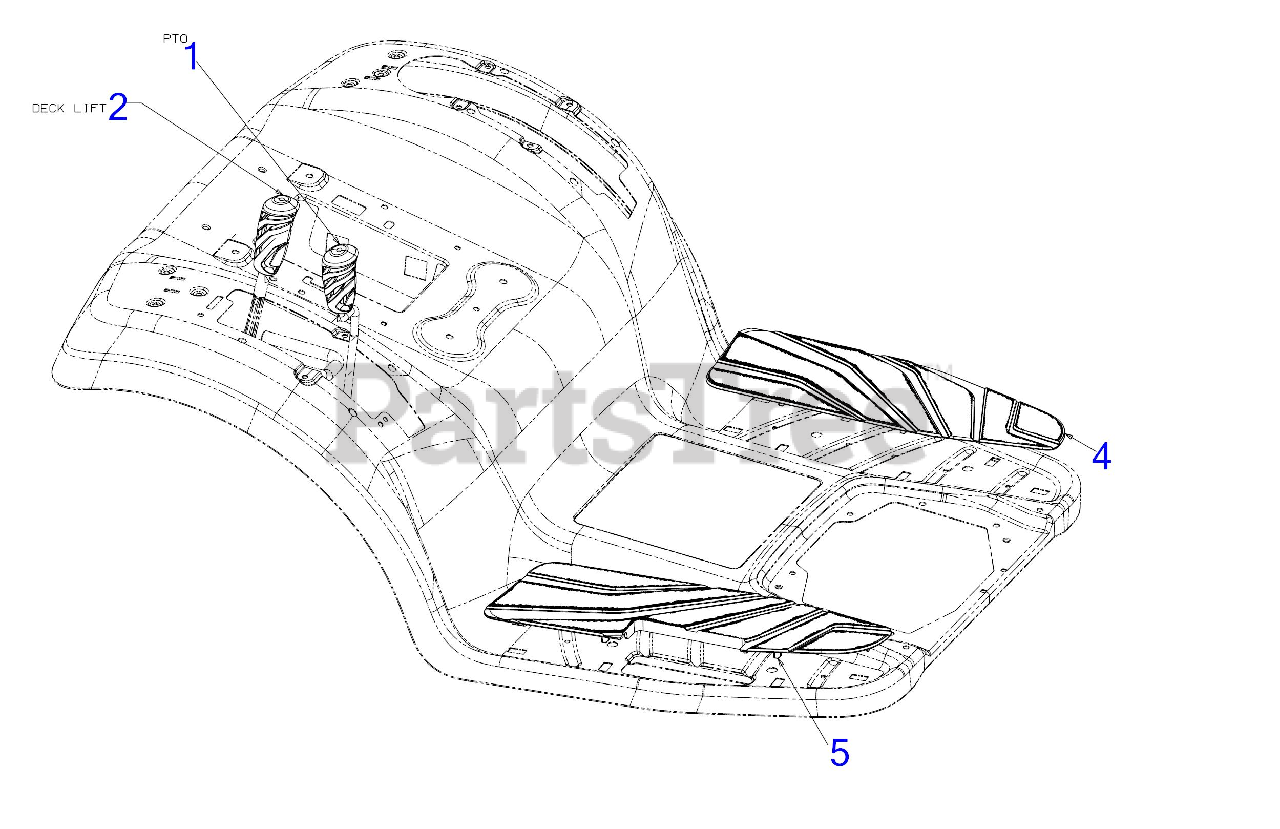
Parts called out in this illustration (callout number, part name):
1	PTO HANDLE GRIP .355 ID
2	LIFT HANDLE GRIP .542 ID
4	FOOTPAD (LH)
5	FOOTPAD (RH)
